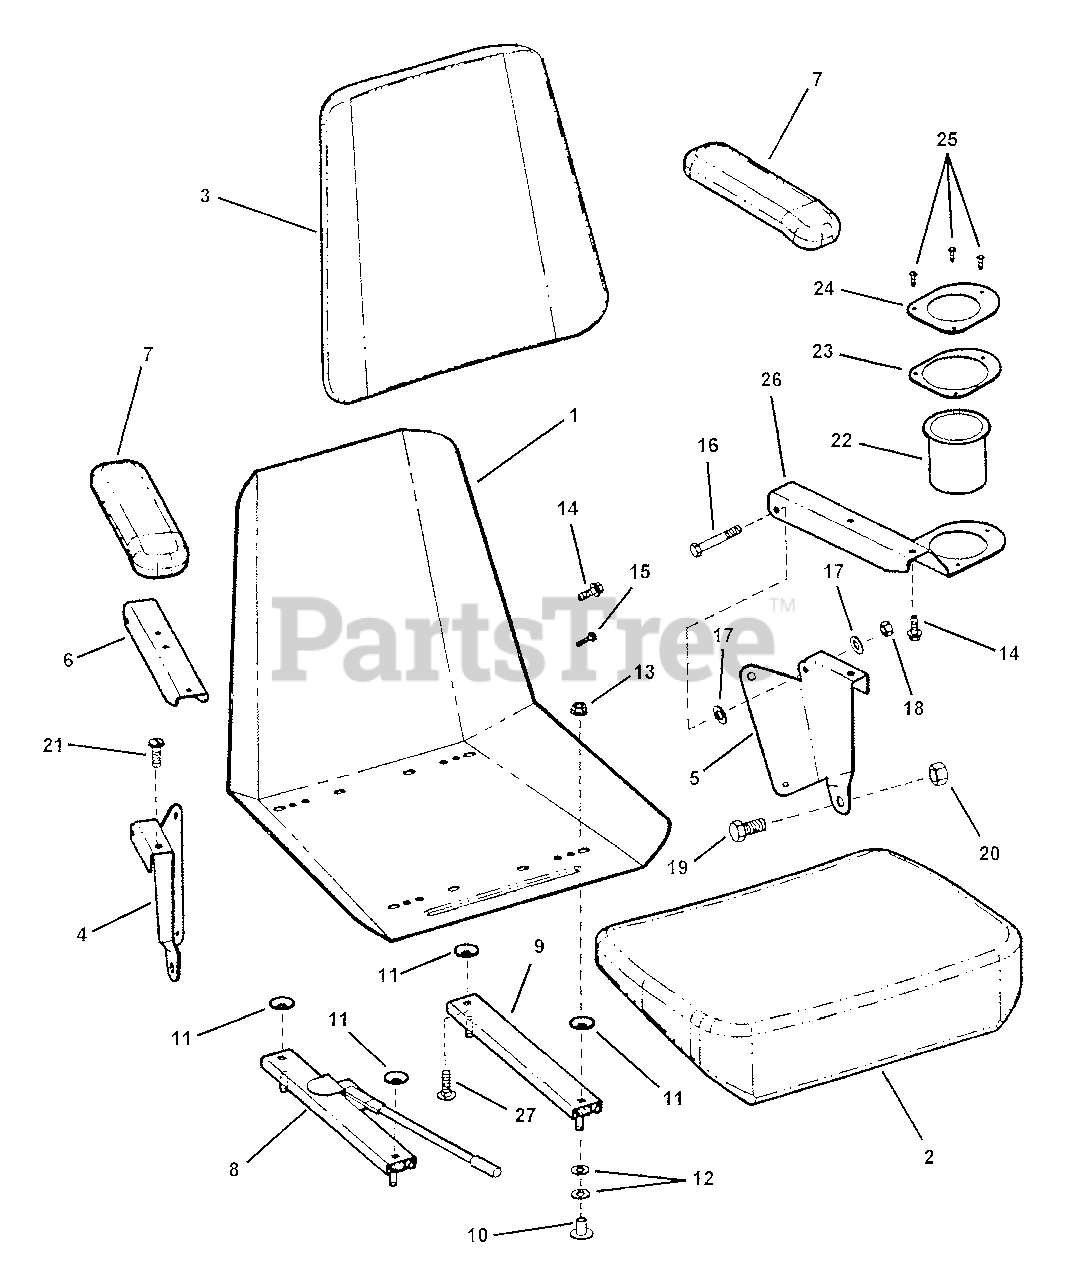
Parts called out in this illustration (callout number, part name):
1	PAN, Complete
2	CUSHION, Seat
3	CUSHION, Back
4	BRACKET, Armrest R.H.
5	BRACKET, Armrest L.H.
6	CHANNEL, Armrest
7	ARM PAD, Grey
8	ADJUSTER (with lock)
9	ADJUSTER (without lock)
10	STUD GUARD
11	SPACER, Bell
12	WASHER, 11/32" Flat, Grade 5
13	NUT, 5/16-18 Hex Flange Grade 5
14	SCREW, 1/4-20 x 3/4" Phillips
15	SCREW, #8 x 1/2" Set
16	BOLT, 5/16-18 X 2", GD5
17	WASHER, .406 I.D. Poly
18	NUT, 5/16-18 Hex Center Lock Grade B
19	SCREW, 1/2-13 x 1" Hex Head Cap, Grade 5
20	NUT, 1/2-13 Hex Head Center Lock, Grade 5
21	SCREW, 5/16-18 x 1" Slotted Pan Head
22	HOLDER, Beverage
23	SPACER, Cup Holder
24	COVER, Cup Holder
25	RIVET, 3/16 Pan Head
26	BRACKET, Arm Rest Cup Holder
27	BOLT, 5/16-18 x 1' Short Neck Carriage Gr. 5
